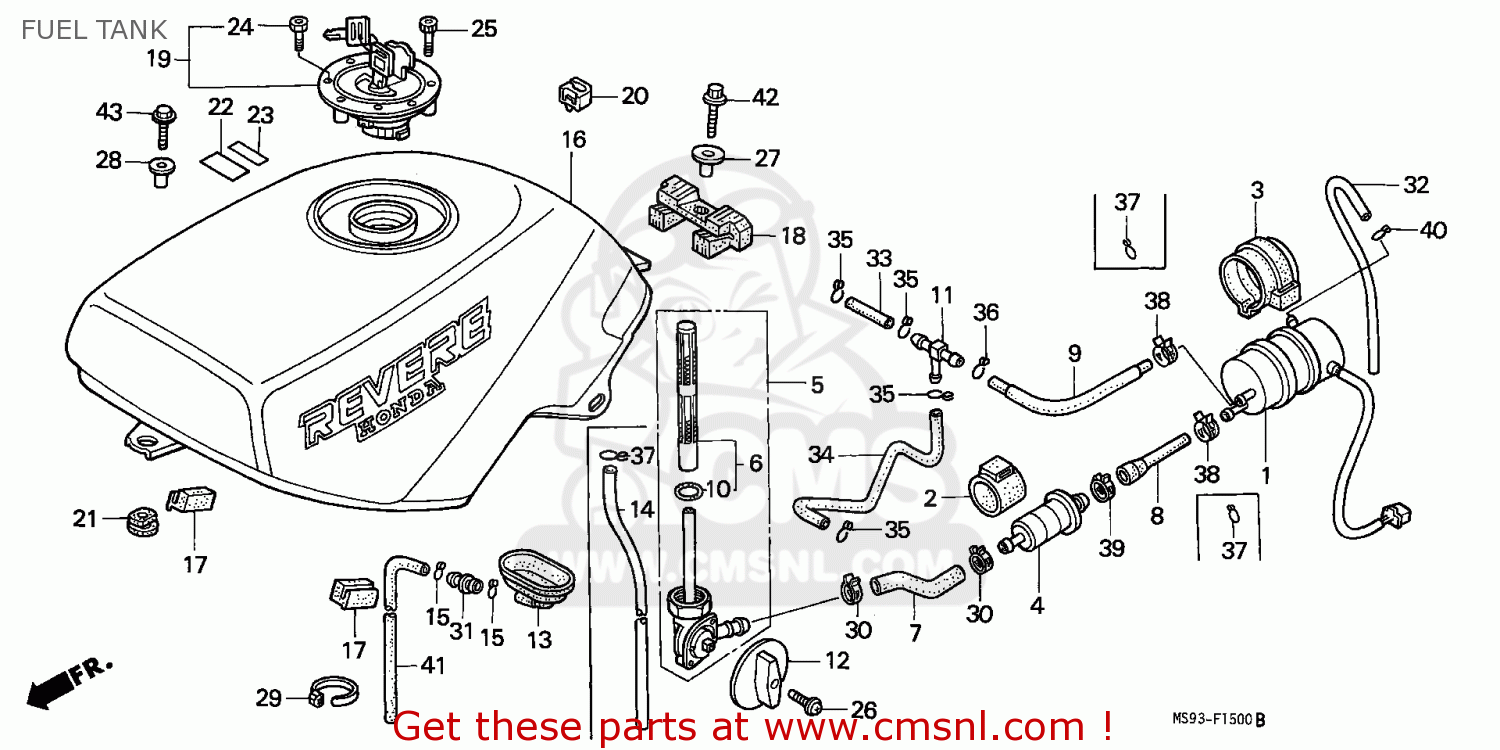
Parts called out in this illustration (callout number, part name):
1	PUMP ASSY.,FUEL (
2	HOLDER,STRAINER
3	RUBBER FUEL PUMP
4	STRN.COMP.,FUEL
5	COCK ASSY.,FUEL
6	SCREEN SET,FUEL S
7	TUBE A,FUEL
8	TUBE B,FUEL
9	TUBE C,FUEL
10	O-RING
11	JOINT,FUEL TUBE
12	LEVER,FUEL COCK
13	TRAY,FUEL TANK DR
15	CLIP,A.BREATHER T
16	TAN*NH193P/TYPE1*
17	RUB.F/TANK SIDE
18	CUSH,FUEL TANK RR
19	CAP COMP.,FUEL FI
20	RUBBER,SEAL BREAT
21	RUBBER,OIL COOLER
22	MARK DRIVE CAUTION
24	BOLT,SOCKET 4X6
25	BOLT,SOCKET,4X21
26	SCREW-WASHER 5X12
27	COLLER,FUELTANK.
28	COLLAR19X6.2X13.5
29	BAND.HARNESS
30	CLAMP. CNSTR HOSE
31	JOINT,TUBE
32	TUBE,FUEL 4.5X360
33	TUBE,FUEL,5.5X40
34	TUBE,FUEL5.3X210
36	CLIP B12,TUBE
38	CLAMP D 12.0 TUBE
39	CLAMP,TUBE,D13
40	CLIP,TUBE 5.0MM
41	TUBE,12X610
42	BOLT,FLANGE,8X28
43	BOLT,FLANGE,6X25
